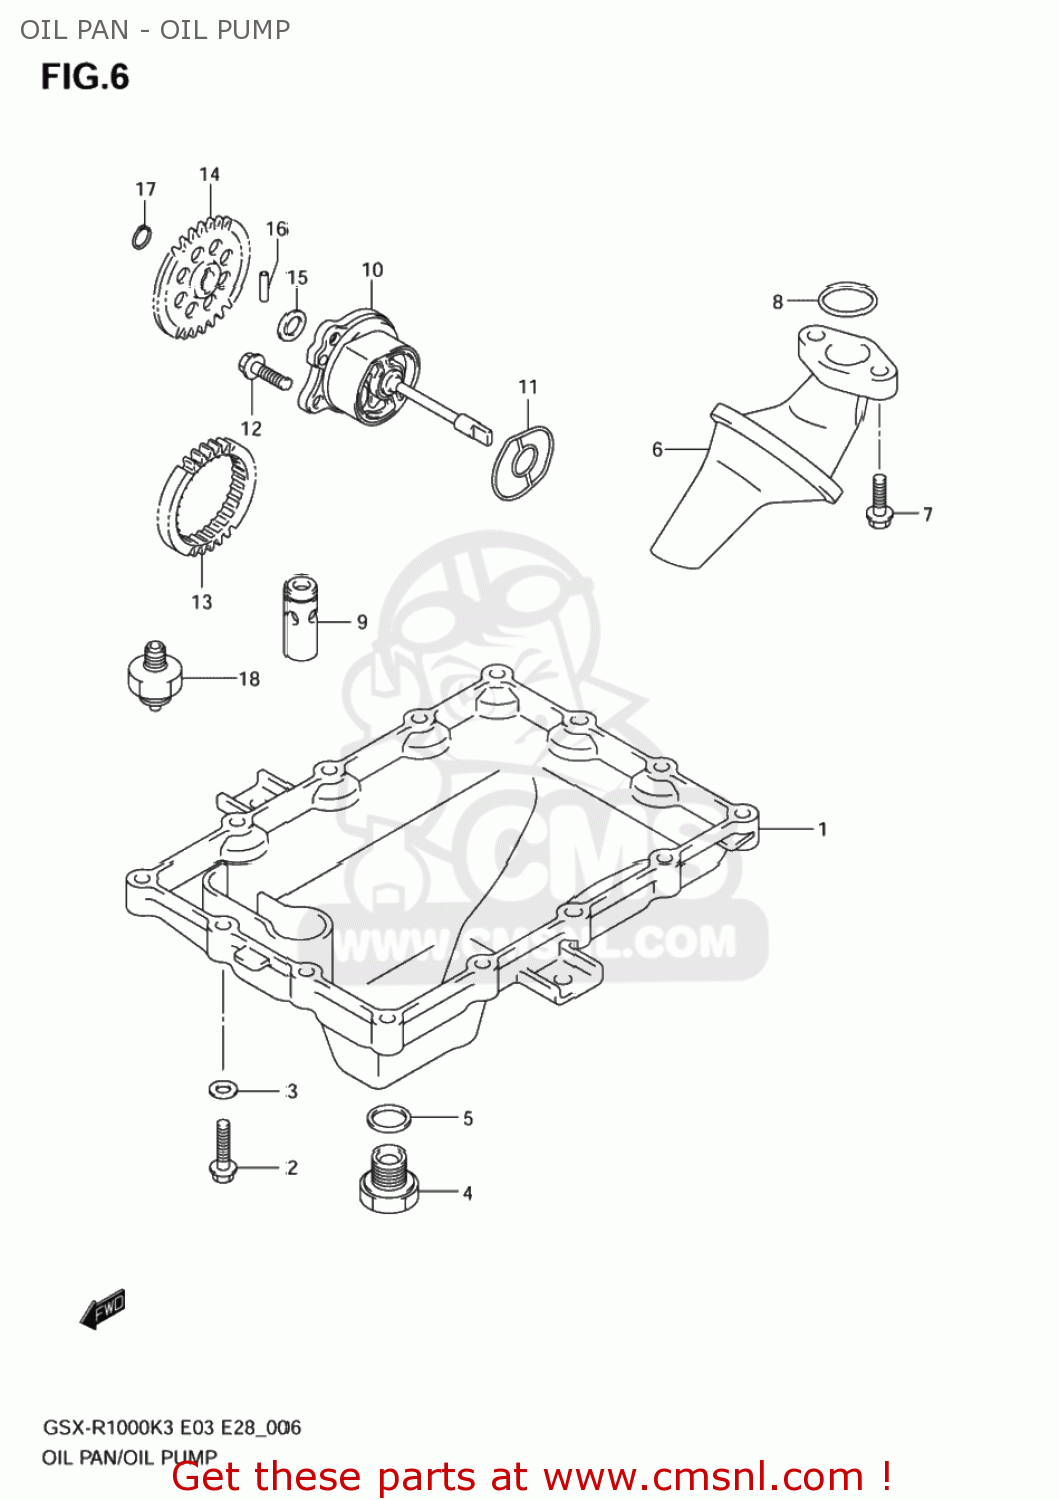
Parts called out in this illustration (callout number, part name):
1	PAN,OIL
2	BOLT(6X25)
3	GASKET(5.8X13X1.2) (NAS)
4	PLUG(14X20)
5	GASKET(13.8X18.8X4.8) (NAS)
6	STRAINER ASSY,ENGINE OIL
7	BOLT
8	O RING(D:2.62,ID:20.3)
9	VALVE ASSY,OIL RELIEF(7K)
10	PUMP ASSY,ENGINE OIL
11	O RING,OIL PUMP
12	SCREW
13	GEAR,OIL PUMP DRIVE
14	GEAR,OIL PUMP DRIVEN
15	SHIM(10X18X0.5)
16	PIN(4X15.8)
17	CIRCLIP,10MM
18	SWITCH ASSY,OIL PRESSURE
